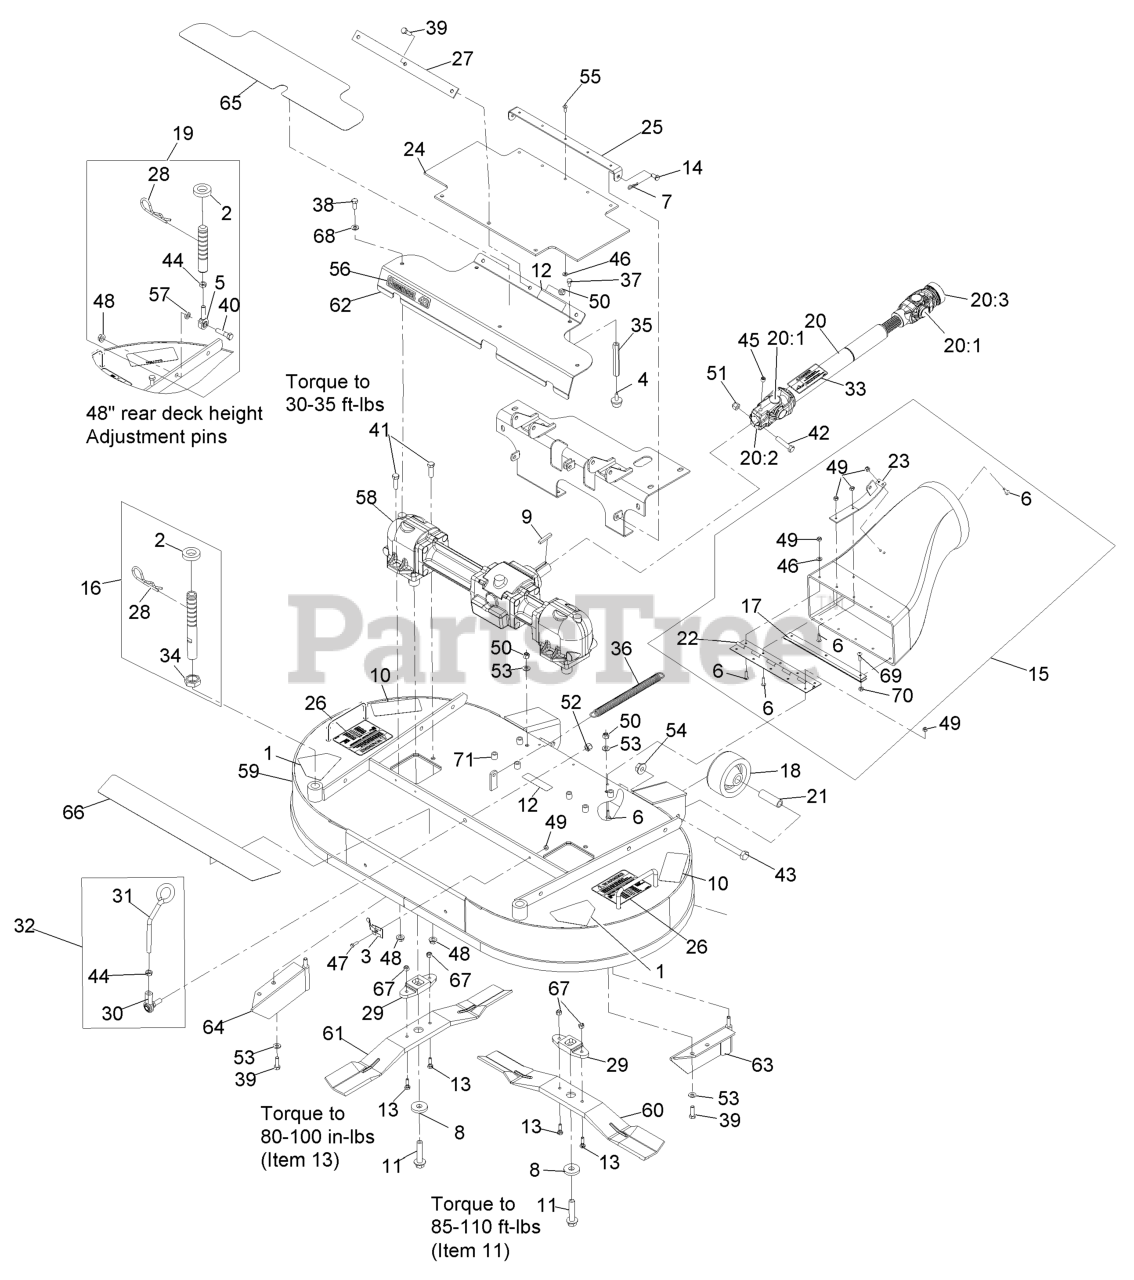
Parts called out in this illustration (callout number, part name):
1	DECAL-DANGER
2	SPACER-DECK SUPPORT
3	CLIP-DECK, HOLD UP ROD
4	BUMPER-RUBBER
5	BALLJOINT
6	SCREW-HEAD, TRUSS
7	PIN-COTTER
9	KEY-SQUARE
10	DECAL-TORQUE
11	BOLT-BLADE
12	DECAL-COVER, MISSING
13	BOLT-SHEAR
14	PIN-CLEVIS
15	DISCHARGE TUBE ASM
16	FRONT DECK HEIGHT ADJUST
17	GUARD-PLENUM
18	ROLLER-DECK
19	REAR DECK HEIGHT ADJUST A
20	DRIVE SHAFT ASM
20:2	YOKE-KEYED
20:3	YOKE-QUICK DISCONNECT
21	SPACER-ROLLER
22	HINGE-PIANO
23	MOUNT-SPRING
24	GUARD-PTO
25	BRACKET-GUARD, PTO
27	STRAP-DRIVE, LINE COVER
28	PIN-CUT HEIGHT
29	DRIVER-BLADE
30	BALLJOINT-RH
31	LATCH-DECK
32	DECK LATCH ASM
33	DECAL-DRIVELINE
34	NUT-JAM
35	STAND-OFF
36	SPRING-EXTENSION
37	SCREW-HH
38	SCREW-HH
39	SCREW-HH
40	SCREW-HH
41	SCREW-HH
42	SCREW-HH
43	SCREW-HH
44	NUT-HEX
45	SCREW-SET, HSH
46	WASHER-FLAT
48	NUT-HHF, WHIZ
49	NUT-LOCK, NI
50	NUT-LOCK, NI
51	NUT-LOCK, NI
52	NUT-LOCK
53	WASHER-SPRING
54	NUT-HHF
55	RIVET-BLIND
56	DECAL,COMMERCIAL 48
57	SPACER-IDLER
58	GEAR BOX ASM
59	DECK DECAL AND BAFFLE ASM
60	BLADE,25 INCH LH
61	BLADE,25 INCH RH
62	ASM,GEARBOX COVER 48 W/DE
63	BAFFLE-LH
64	BAFFLE-RH
65	PAD-ANTI SKID
66	PAD-ANTI SKID
67	NUT-LOCK, NI
68	WASHER-PLAIN
69	BOLT-CARR
70	NUT-LOCK, NI
71	NUT-CLINCH
